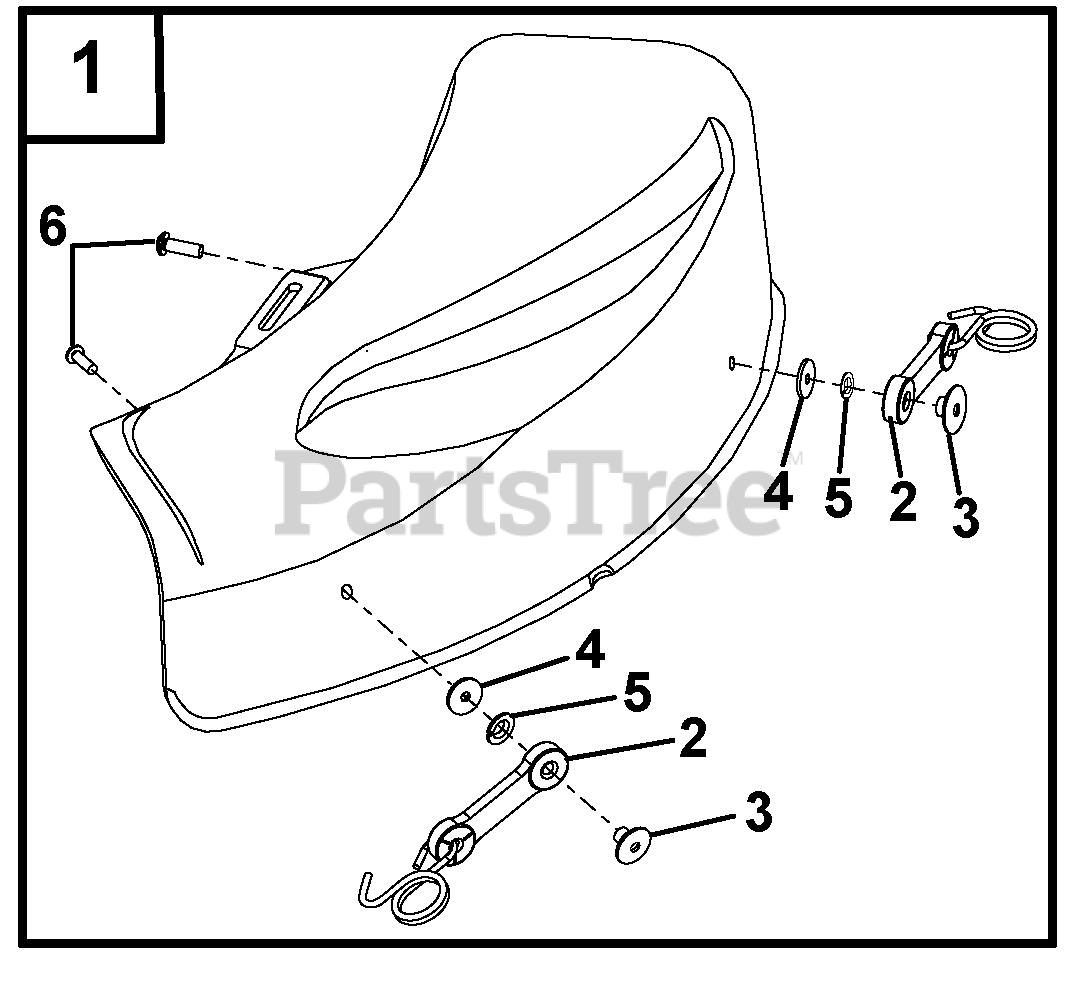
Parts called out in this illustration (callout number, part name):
1	Mulch Cover Assembly (Complete)
2	Latch Hook
3	Weld Nut
4	Washer 3/16 X 3/4
5	Washer, Lock #10
6	Screw #10 X 5/8
